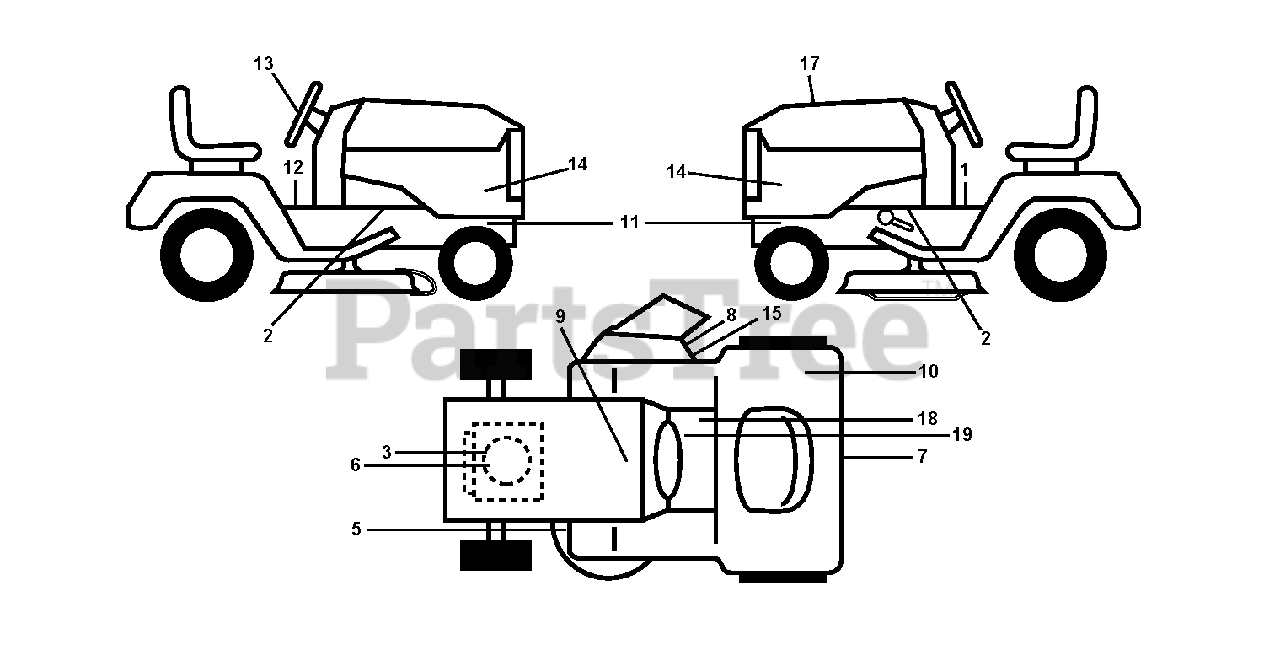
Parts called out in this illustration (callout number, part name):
5	DECAL.MOWER.SCH.48/54
8	DECAL.INTERNATIONL.CUTFINGER
9	DECAL BTRY SYMBOLS
10	DECAL.FENDER
15	DECAL, DEFLECT WARNING
19	DECAL PARK BRAKE
